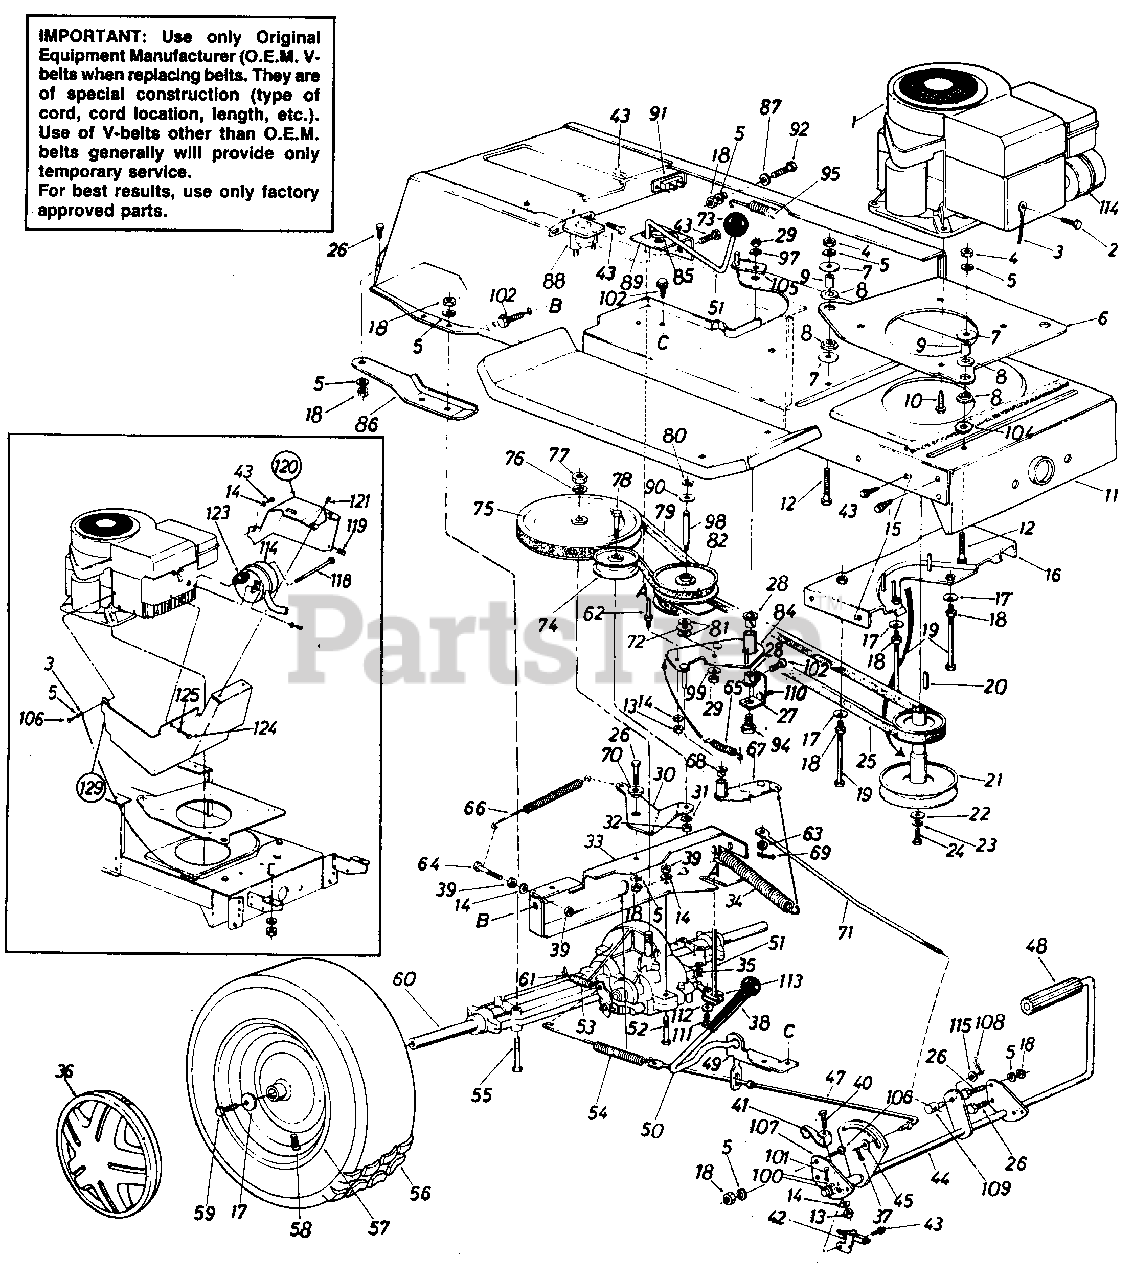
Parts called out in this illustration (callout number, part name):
1	Engine
2	Hex Bolt 1/4-20 x .62" Lg.
3	Electric Ground Wire
4	Hex Nut 5/16-24 Thd.
5	L-Wash. 5116" I.D.*
8	Engine Mounting Grommet
9	Spacer
10	Hex Bolt 3/8-16 x 1.25" Lg.
11	Lower Frame Ass'y.
12	Hex Bolt 5/16-24 x 1.25"*
13	Hex Nut 1/4-20 Thd.
14	L-Wash. 1/4" I.D.*
15	Hex Wash. Hd. AB-Tap Scr. 5/16" x.75" Lg.
16	Belt Guard Brkt. Ass'y.
17	Bell-Wash. .345" I.D. x .88"
18	Hex Nut 5/16-18 Thd.
19	Hex Bolt 5/16-18 x 4"*
20	Sq. Key 1/4" x 1/4" x 2.00"
21	Engine Pulley
22	Fl-Wash. 7/16" I.D. x 1.25"
23	L-Wash. 7/16" I.D.*
24	Hex Bolt 7/16-20 x 1.50" Lg.
25	Variable-Speed Belt
26	Hex Bolt 5/16-18 x .75" Lg.
27	Bearing Shaft Bracket Ass'y.
28	Flanged Nyliner Brg. 518" I.D. x .88" Lg.
29	Hex Nut 3/8-24 Thd.
30	Idler Bracket
31	L-Wash. 3/8" I.D.*
32	Hex Nut 3/8-24 Thd.*
35	Inter. Cott-Pin
36	Hub Cap
37	Cotter Pin 3/32" Dia. x .75"*
39	Hex Nut 1/4-28 Thd.
40	Hex Bolt 1/4-20 x 1.00" Lg.
41	Switch Actuator
42	Safety Switch
43	Hex Wash. Hd. S-Tap Scr. 1/4-20 x .50" Lg.
44	Clutch/Brake Pedal Ass'y.
45	Fl-Wash.
47	Brake Rod 20.9" Lg.
48	Foot Pad
49	Brake Lever Bracket
50	Hill Holder Brake Handle
51	Shift Lever Ass'y.
52	Hex Bolt 1/4-28 x 1.75" Lg.*
53	Ext. Spring .38" O.D. x 2.5"
54	Ext. Spring .59" O.D. x 7.08"
55	Hex Bolt 5/16-18 x 2.75"*
58	Air Valve
59	Hex Bolt 5/16-24 x .75" Lg.*
60	Transaxle Complete
61	Brake Return Spring Anchor
62	Belt Guard Pin 1/4-20 Thd.
63	Fl-Wash. .34" I.D. x .68" O.D.
64	Hex Bolt 1/4-28 x 1.25" Lg.*
65	Ext. Spring
66	Ext. Spring .62" O.D. x 6.12"
68	Flanged Bearing
69	Cotter Pin 3/32" Dia.*
70	Shoulder Spacer .27" Lg.
71	Speed Control Link
72	Truss Bearing .56 Dia. x 1.25"
73	Ball Knob
74	Fl-ldler Pulley 3.25" x .75"
75	1/2" "V"-Pulley 8.0" O.D. x .501 " I.D.
76	L-Wash. 1/2" I.D.*
77	Hex Jam Nut 1/2-20 Thd.*
78	Hex Bolt 3/8-24 x 1.75" Lg.
79	Variable Speed Belt
80	Snap Ring .56" Dia.
82	Variable Speed Pulley Ass'y. 5" O.D.
86	Axle Support Brkt.-R.H.
87	Fl-Wash. .34 I.D. x 1.12 O.D.
88	Solenoid
89	Shift Lever Bracket
90	Teflon Washer .565" I.D.
91	Circuit Breaker
92	Hex Bolt 5/16-18 x 1.50" Lg.
94	Shld. Bolt 3/8-24 x 3.12" Lg.
95	Ext. Spring .99" O.D. x 11"
97	Bell-Wash. .38" I.D. x .88"
98	Shaft .56" Dia. x 3.875" Lg.
99	Bell-Wash. .39" I.D. x 1.12"
100	Fl-Wash.
101	Cotter Pin 3/32" Dia. x 1.0"*
102	Hex Wash. Hd. Scr. 5/16-18 0 x.62" Lg.
104	Fl-Wash. .32" I.D. x 1.25"
105	Belt Guard
106	Truss Mach. Scr. 5/16-18 x .75" Lg.*
107	Pedal Bracket
108	Cotter Pin 3/32" Dia. x .75"
109	Ferrule
110	Hex Bolt 5/16-18 x 1.0" Lg.- 0 (Gr. 5)
111	Hex Bolt 1/4-28 x .50" Lg.
112	Bell-Wash. .265" I.D. x .75"
113	Shift Lever Link Ass'y.
114	Muffler
115	Fl-Wash. .385" I.D. x .62" O.D.
118	Shld. Bolt 5/16-18 Thd.
119	Speed Nut #10-24 Thd.
120	Muffler Heat Shield-L.H.
121	Hex AB-Tap Scr. #10 x .5" Lg. Hex Bolt 1/4-20 x .85" Lg.
123	Gasket
124	Hex Bolt 1/4-20 x 3/8" Lg.
125	Spr. Wash. .265" I.D. x .562" Spacer .28" I.D. x .5" O.D.
129	Muffler Heat Shield-Front
